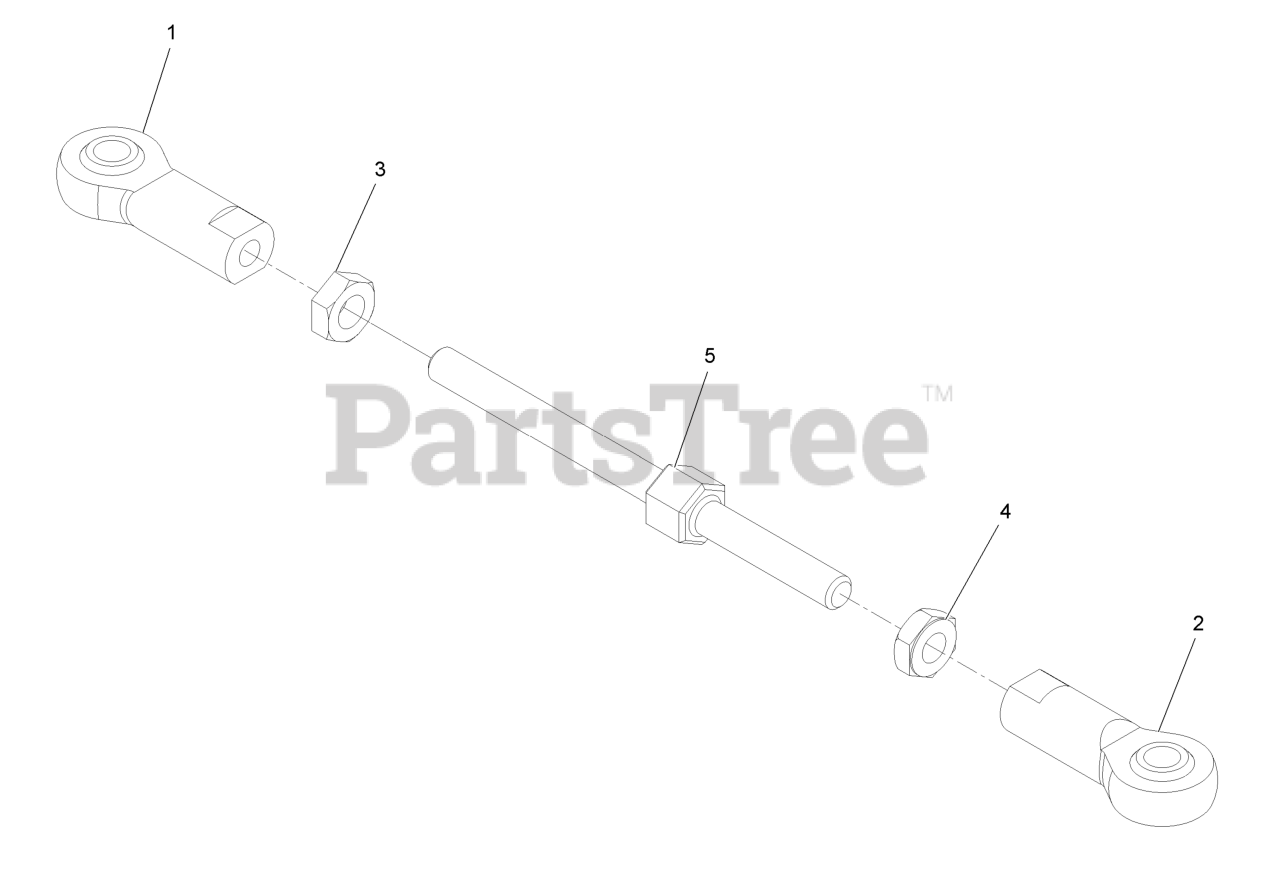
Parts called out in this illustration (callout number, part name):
1	Rod End-Ball Joint
2	Joint-Ball, LH
3	Nut-Jam 1/4-28
4	Nut-Jam
5	Rod-Vertical Adjust
